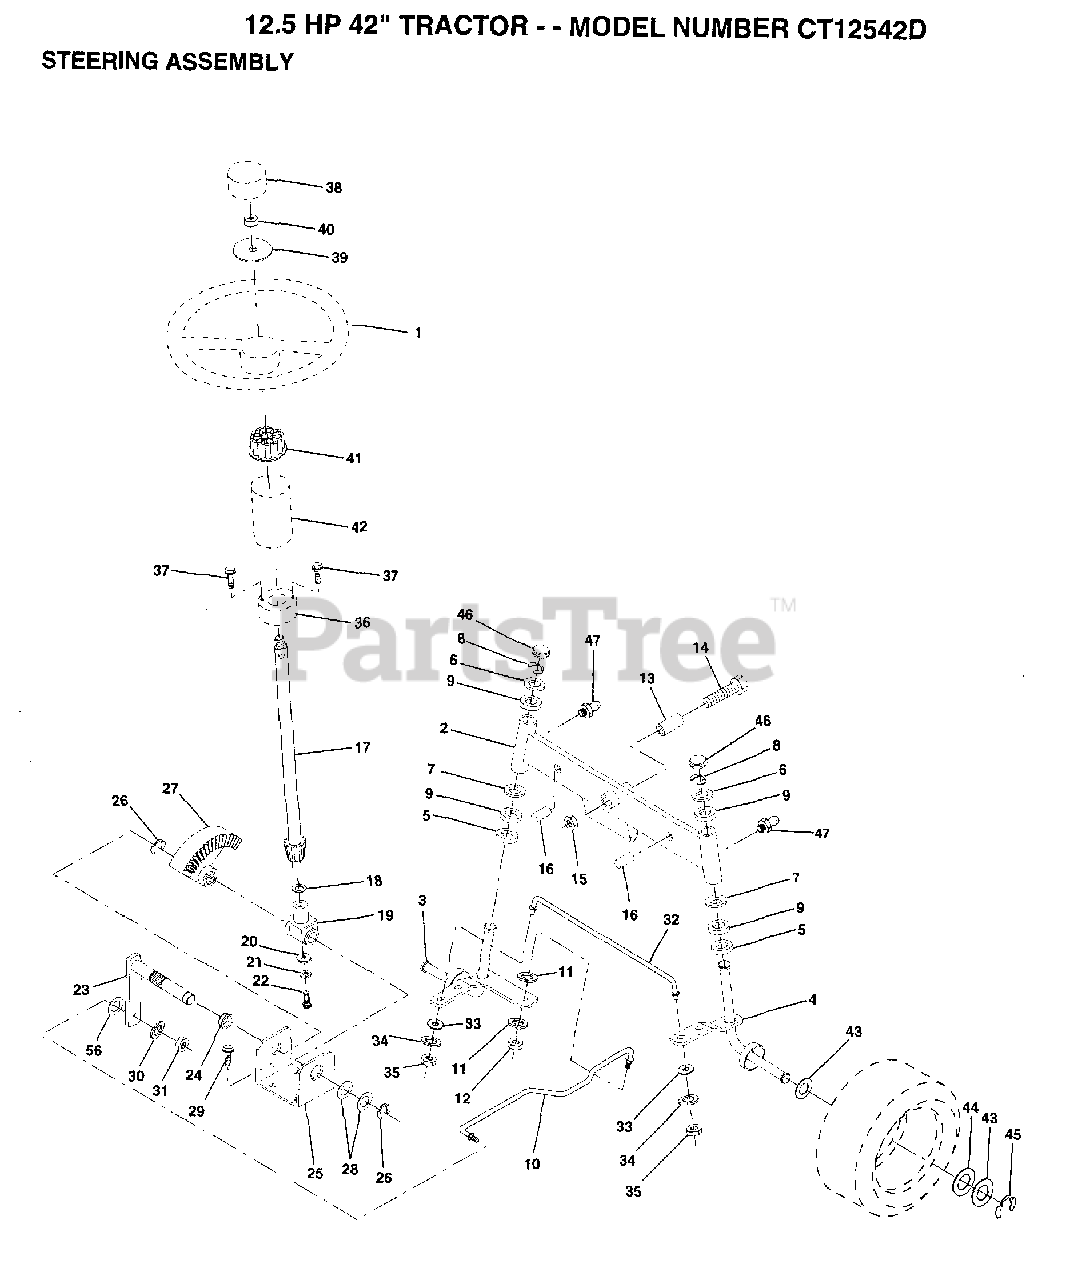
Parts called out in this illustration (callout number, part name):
1	WHEEL STR AYP BLK
2	AXLE ASM FRONT
3	SPINDLE LH
4	SPINDLE RH
5	WASHER .T
6	WASHER
7	WASHER
8	RING
9	COL. SRTG. BEAR.
11	LOCKWASHER
13	BEARING
15	"NUT-LOC,FLANGE LT"
16	AXLE PIN
17	SHAFT ASM
18	THRUST WASHER
19	SUPPORT.SHAFT
21	LOCKWASHER
22	"SCREW,SPECIAL"
24	NYLINER T
25	"BRKT,STEERING"
26	RING
27	GEAR SECTOR
28	WASHER .T
29	SCREW
30	LOCKWASHER
32	ROD.TIE.19.75
33	WASHER M
34	LOCKWASHER
35	NUT.LOCK.5/16-24
38	CAP STEER AYP
39	WASHER T
40	GRIPCO NUT
41	ADAPTER-WHEEL LT
42	"TUBE, STR SHAFT"
43	WASHER
44	WASHER
45	RING
46	CAP
47	ZERK M
56	WASHER
